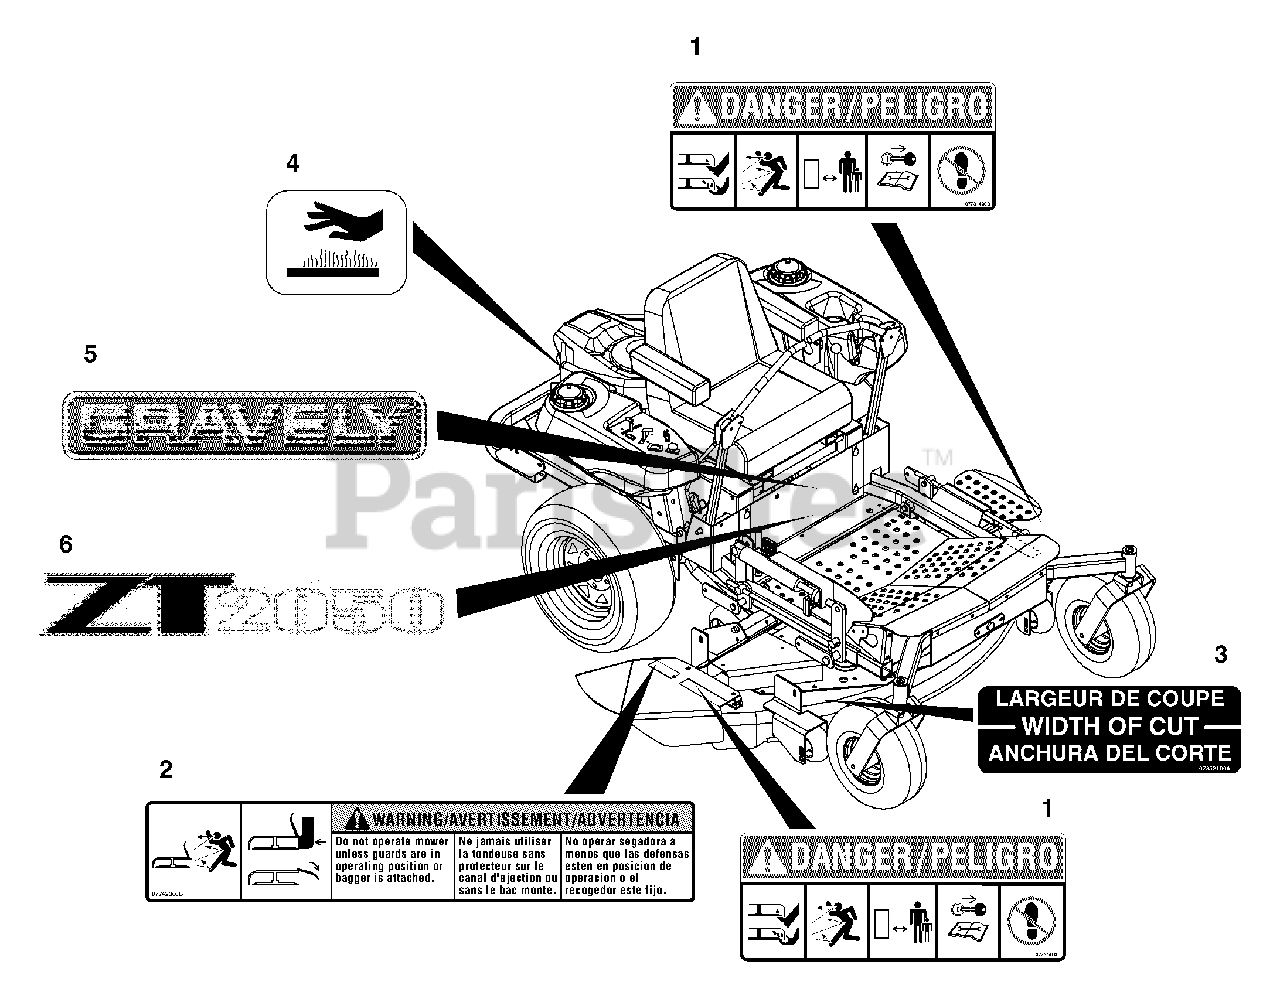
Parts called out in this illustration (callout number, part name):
1	Decal, Mower Pan Head Danger
2	Decal, Warning
3	Decal, Width of Cut
4	Decal-Hot Surface
5	Decal, 15" Gravely Logo
6	Decal, Gravely ZT2050 Logo
